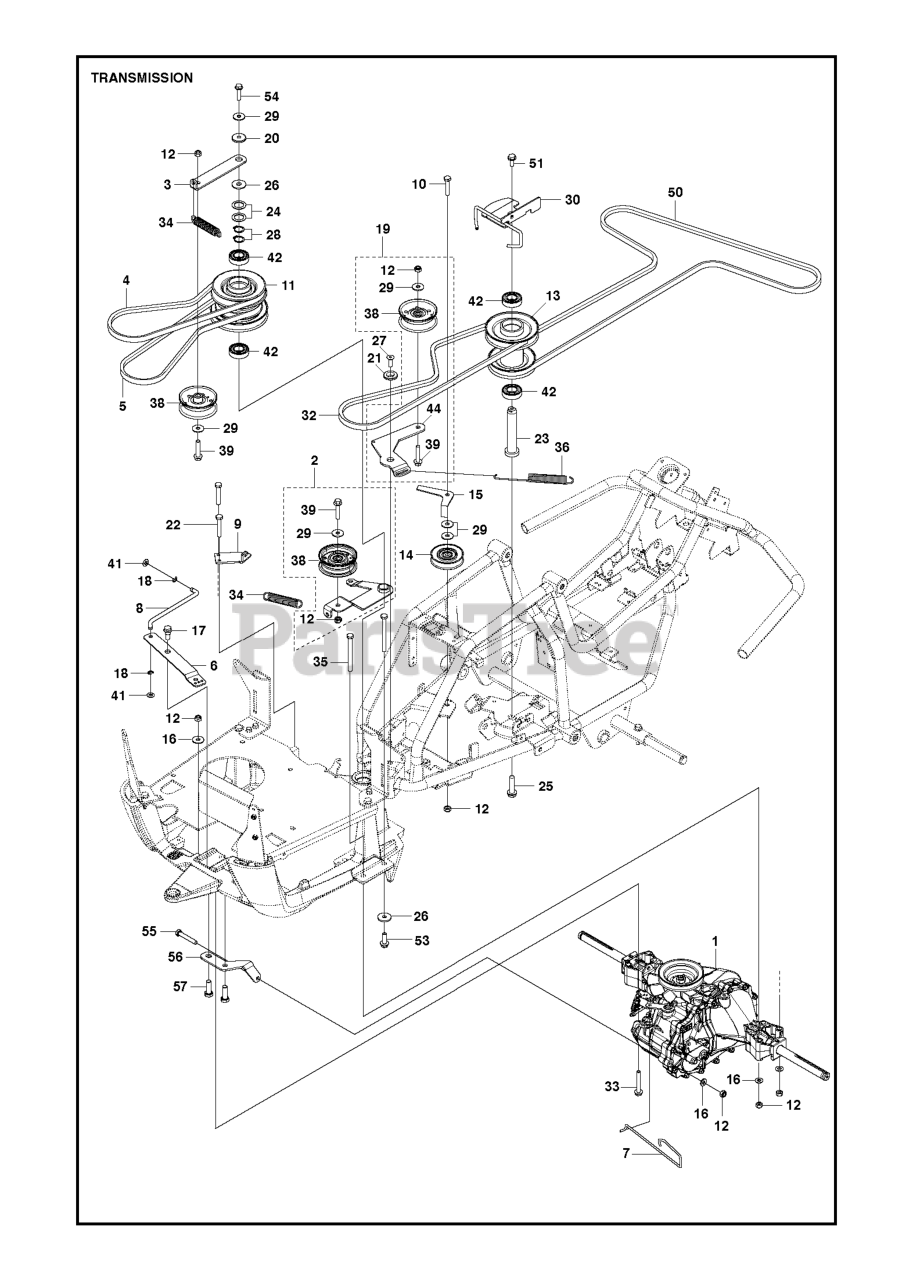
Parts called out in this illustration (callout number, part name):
1	TRANSMISSION T36P HYDROSTATIC
5	BELT
6	LINK ARM
7	ARM
8	ROD
12	LOCKNUT M8
16	WASHER BRB 8.4X17
19	BELT TENSIONER
20	WASHER
22	BOLT FLANGE - M6X20
28	RETAINING RING SGA 20
33	SCREW EHHFM
38	IDLER PULLEY
42	BALL BEARING 6004-2RS1
44	BELT TENSIONER
54	SCREW EHHFM
